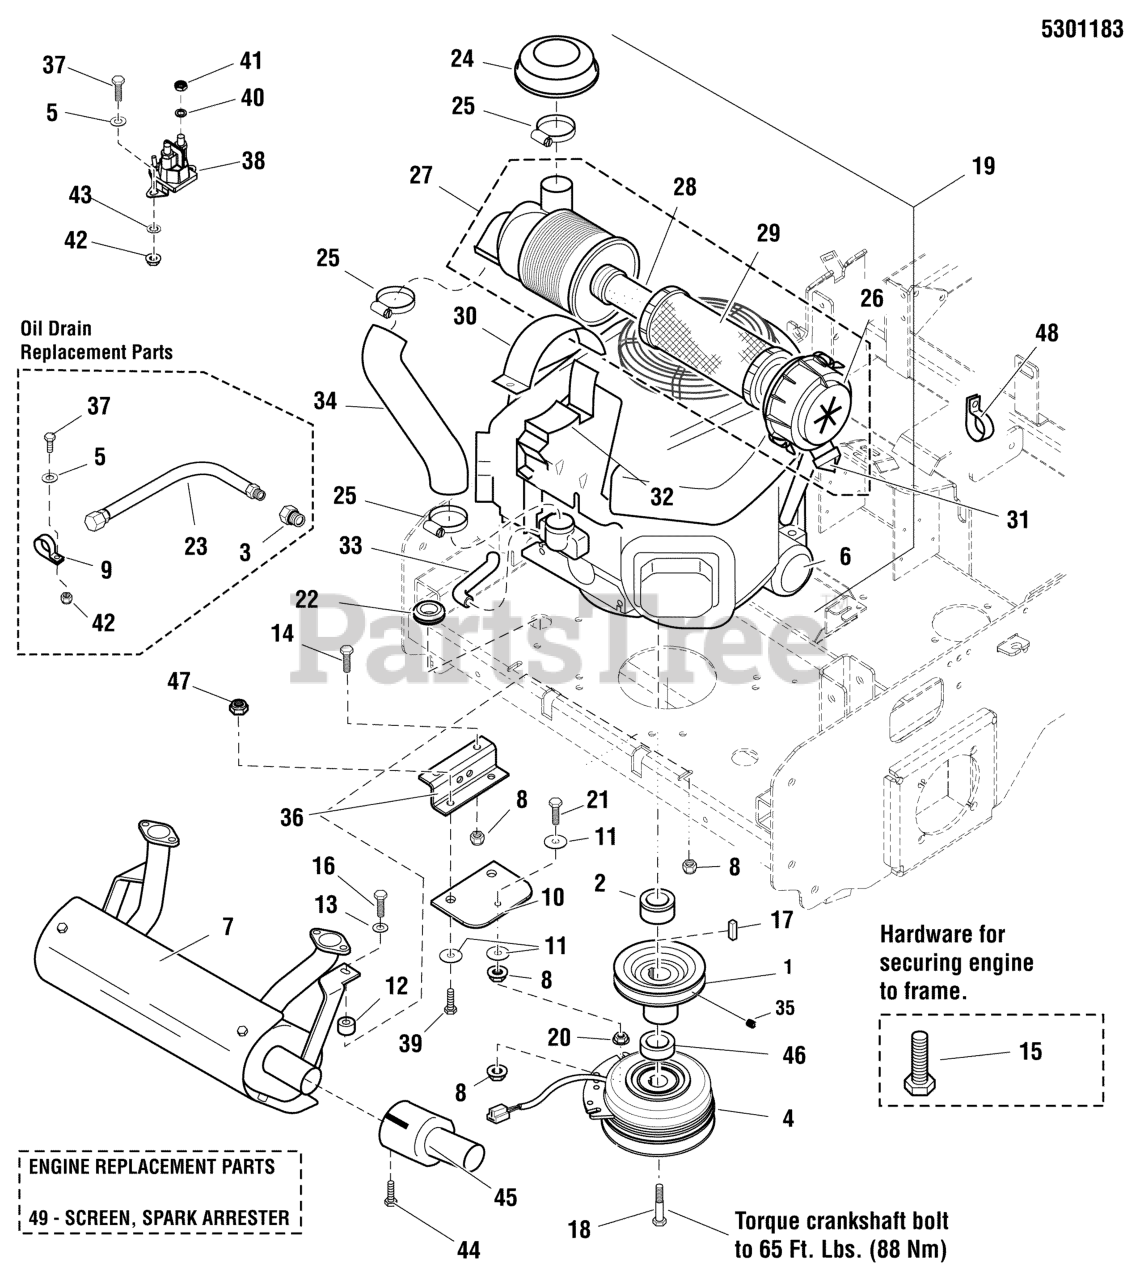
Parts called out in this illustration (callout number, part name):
1	PULLEY, 5.15 OD X 1-1/8 BORE B-SECT
2	SPACER, 1.13 X 1.75 X 1.03
3	ADAPTER, OIL DRAIN
4	* CLUTCH, 5218-134, WARNER
5	WASHER, 1/4 SAE
6	FILTER, OIL, 22, 24 & 26 HP, KAWASAKI
7	MUFFLER, KAWI, HORIZONTAL, 5" CAN
8	NUT, 5/16-18 HEX NYLOCK FLANGE
9	CLAMP, VINYL INSULATED
10	CLUTCH ANCHOR PAD
11	WASHER, .34 X 1.25 X 10 GA
12	SPACER, .39 X 1.00 X .80
13	WASHER, 5/16" SAE
14	BOLT, 5/16-18 X 1 GD5 YZ
15	BOLT,HEX FLG,SER GD5 3/8-16X1-1/4PACH CZ
16	BOLT, 5/16-18 X 1-3/4 GD5 YZ
17	KEY, 1/4 SQ X 1
18	BOLT, CRANKSHAFT, 7/16"X2-1/2
20	NUT, 5/16-18 HEX SERRATED FLANGE (LARGE)
21	BOLT, 5/16-18 X 2-1/4 TFL, GD5 YZ
22	GROMMET, 7/8
23	HOSE, OIL DRAIN
24	RAIN COVER (SV)
25	CLAMP (SV)
26	AIR FILTER CAP END (SV)
27	AIR FILTER ASSEMBLY, COMPLETE (SV)
28	AIR FILTER, SECONDARY (SV)
29	AIR FILTER, PRIMARY (SV)
30	CASE BRKT,AIR FILTER,22,24&26HP KAWASAKI
31	RUBBER, DUST VALVE (SV)
32	CASE BRKT,AIR FILTER,22,24&26HP KAWASAKI
33	BREATHER TUBE (SV)
34	AIR INLET TUBE (SV)
35	SET SCREW, 5/16-18 X 3/8, KNURL, W/PATCH
36	ANCHOR, CLUTCH - BLK
37	BOLT, 1/4-20 X 3/4 GD5 YZ
38	SOLENOID-4 POLE 12 VOLT DC (TROMBETTA)
39	BOLT, 3/8-16 X 1" GD5 CZ
40	WASHER, 5/16 LIGHT LOCK (SV)
41	NUT, 5/16-24 JAM (SV)
42	NUT, 1/4-20 HEX NYLOCK FLANGE
43	WASHER, 1/4 INTERNAL TOOTH LOCK
44	SCREW,SELF-TAP,#8-32 X 3/8,WASH HEX, CZ
45	EXTENSION, TAILPIPE, 3" - BLACK
46	SPACER, 1.13 X 1.75 X .62
47	NUT, 3/8-16 HEX NYLOCK FLANGE
48	CLAMP, HOSE, 1.000 DIA
